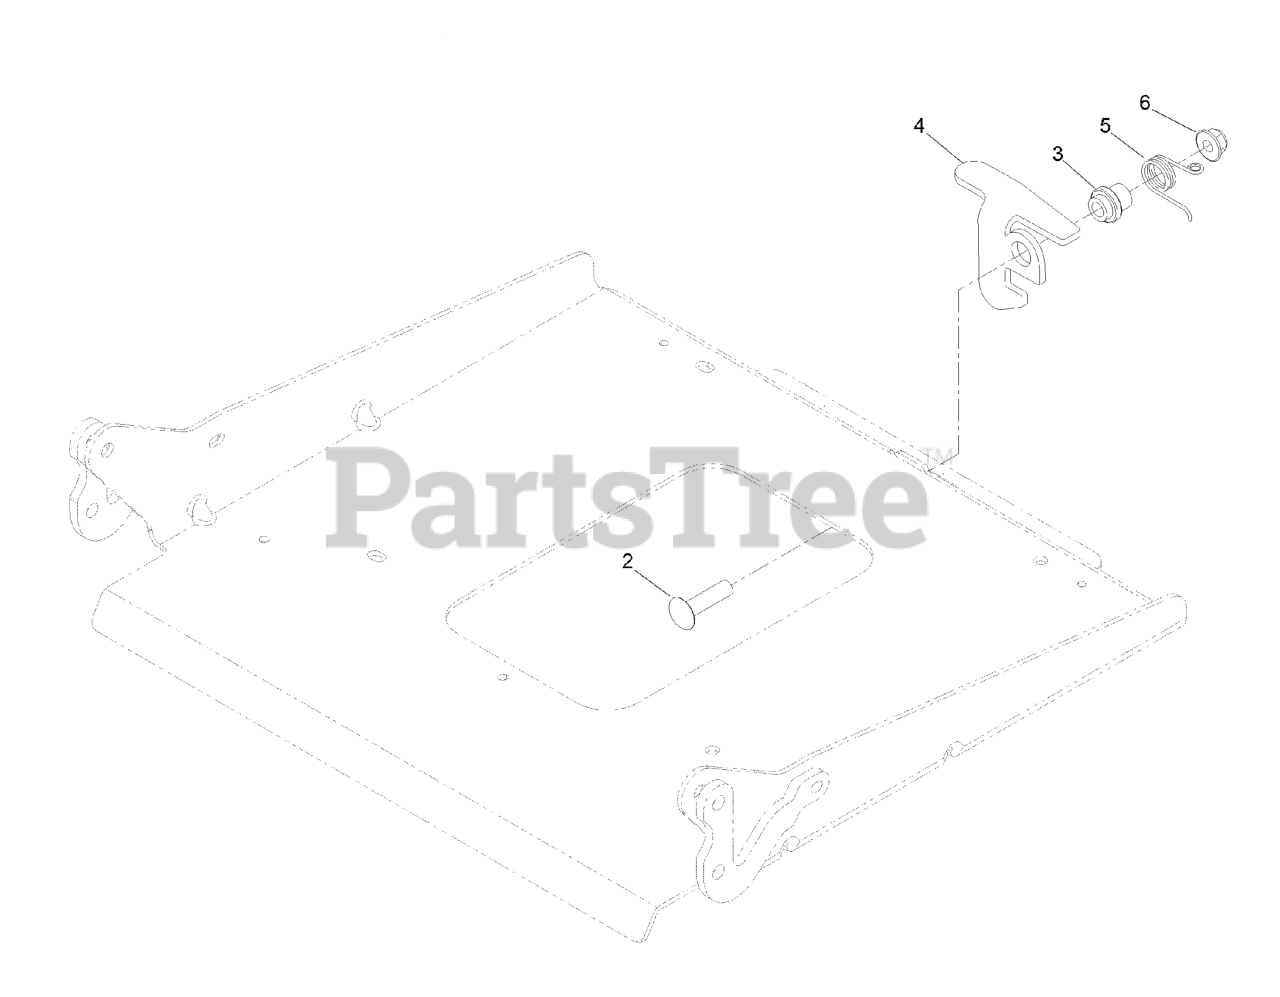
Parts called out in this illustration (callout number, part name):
2	SCREW-CARR
3	BUSHING-LATCH, SEAT
4	LATCH-CATCH, SINGLE
5	SPRING-TORSION, LATCH
6	NUT-HF, NI
